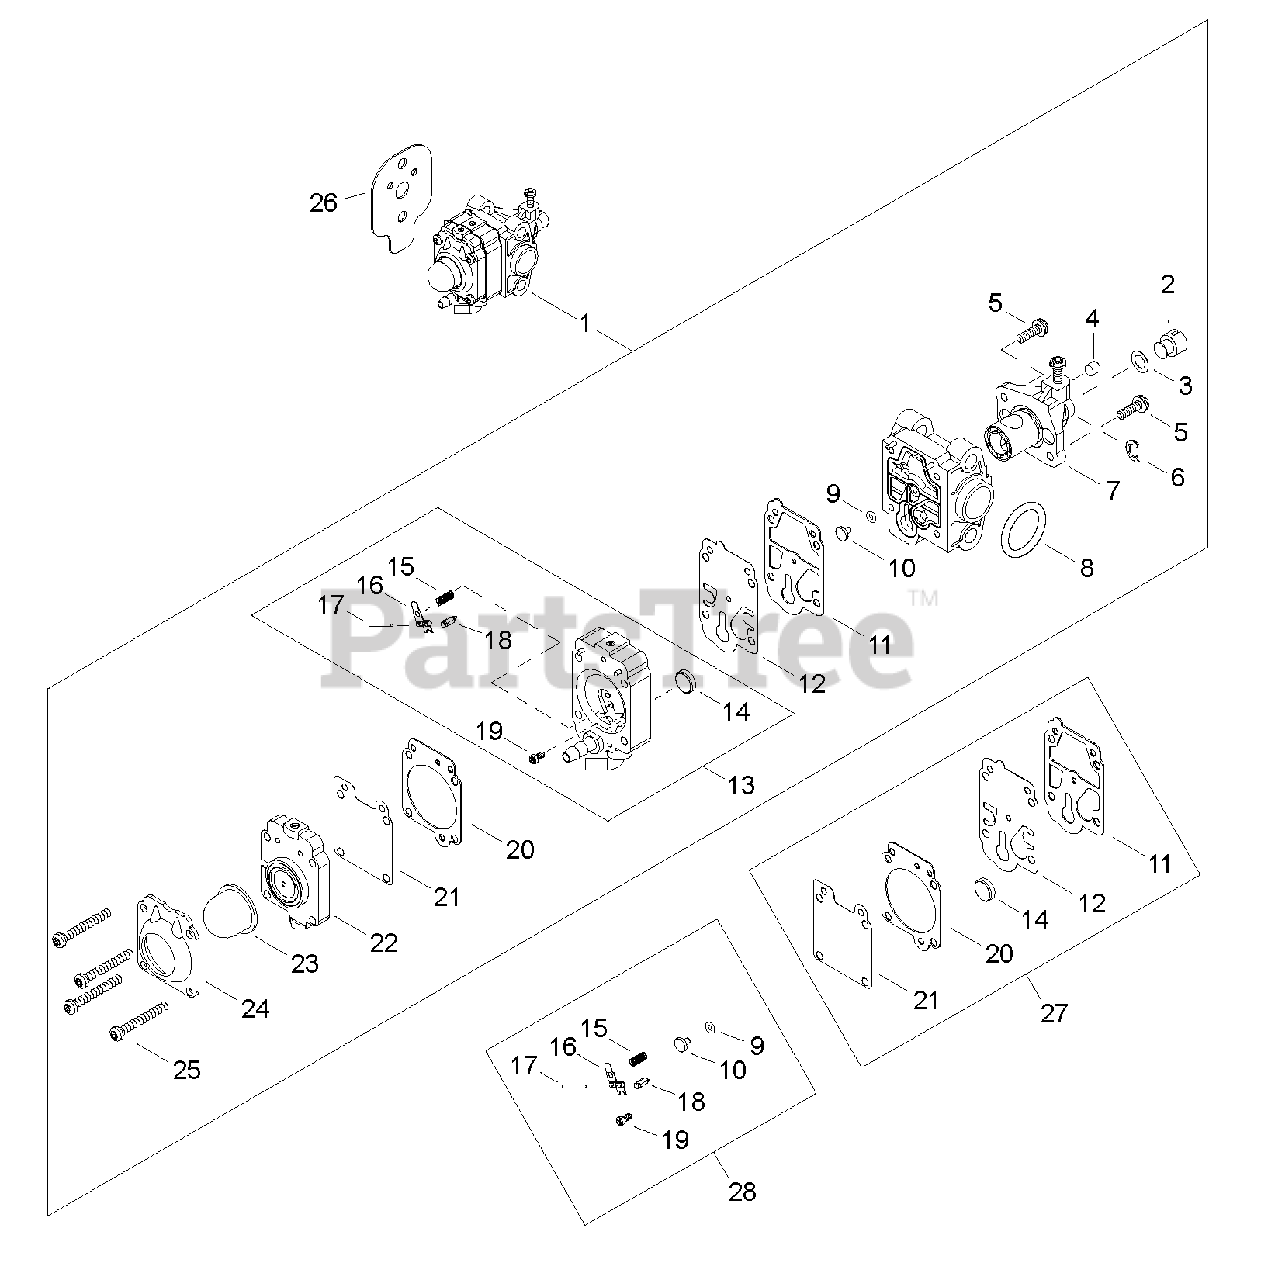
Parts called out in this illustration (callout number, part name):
1	CARBURETOR
2	SWIVEL
3	WASHER
4	PLUG
5	SCREW, THROTTLE COLLAR
6	E-RING
7	VALVE ASSY, THROTTLE
8	O-RING 15
9	O-RING
10	JET, MAIN
11	GASKET, PUMP
12	DIAPHRAGM, PUMP
13	BODY ASSY, PUMP
14	SCREEN, FUEL INLET
15	SPRING, METERING LEVER
16	LEVER, METERING
17	PIN, METERING LEVER
18	VALVE, INLET NEEDLE
19	SCREW
20	GASKET, METERING DIAPHRAGM
21	DIAPHRAGM, METERING
22	BODY ASSY, PURGE
23	BULB, PURGE
24	RETAINER, PURGE BULB
25	SCREW
26	GASKET, INTAKE
27	GASKET / DIAPHRAGM KIT
28	VALVE KIT, INLET NEEDLE
